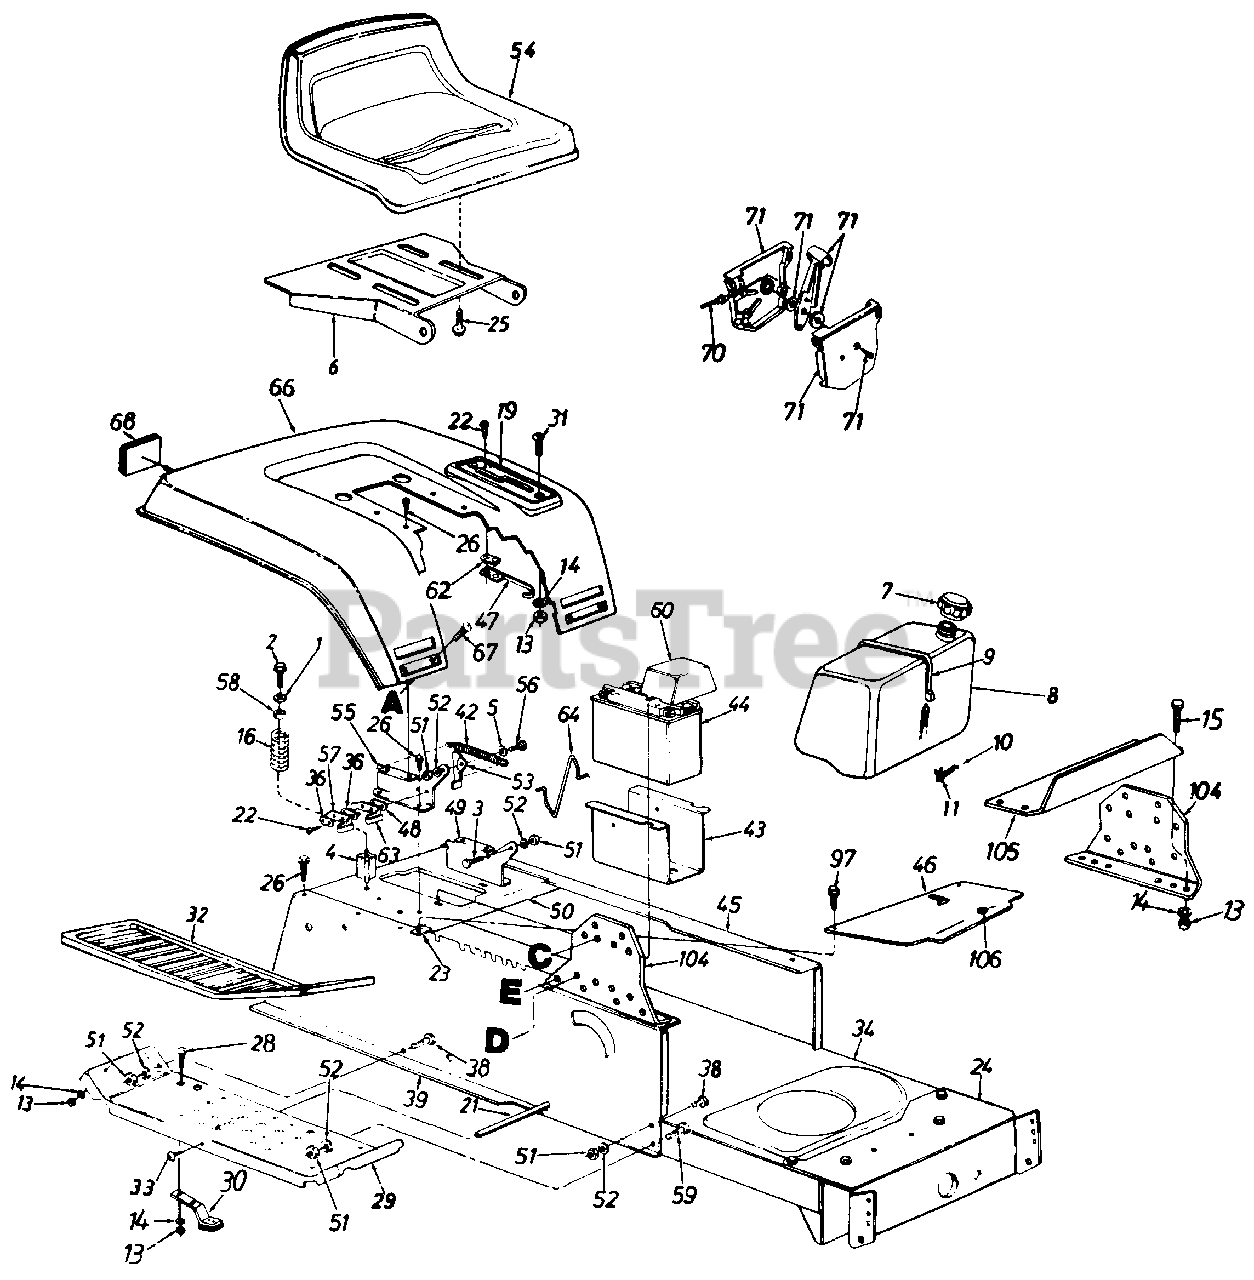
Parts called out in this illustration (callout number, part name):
1	Fl-Wash. .344" I.D. x .875"
2	Hex Wash. Hd. Tap Scr. 5/16-18 x 3.25" Lg.
3	Shld. Bolt .437" Dia. x .162"
4	Spring Spacer
5	Spr-Wash. .445" I.D. x .75
6	Seat Pivot Bracket
7	Fuel Cap w/o Gasket
8	Fuel Tank
9	Tie Strap
10	Fuel Line 15" Lg.
13	Hex Nut 1/4-20 thd.
14	L-Wash. 1/4" I.D.
15	Hex Bolt 1/4-20 x .62" Lg.
16	Compression Spring
19	Speed Control Index Brkt.
21	Running Board Rod
22	Hex Wash. Hd. AB-Tap Scr. #8 x .50" Lg.
23	Speed Nut #10Z
24	Front Pivot Bar
25	Hex Tap Scr. 3/8-16 x .75"
26	Hex Wash. Hd. AB-Tap Scr. 5/16 x .75" Lg.
28	Carriage Bolt 1/4-20 x .62"
29	Running Board (R.H. & L.H.)
30	Blade Brake Ass'y.
31	Truss Mach. Scr. 1/4-20 x .75" Lg.
32	Rubber Foot Pad-L.H.
33	Pan Hd. Cutting Scr. 5/16-18 x .75" Lg.
34	Lower Frame
36	Insulator Plate
38	Hex Bolt 5/16-18 x .75" Lg.
39	Upper Frame-R.H.
42	Extension Spring 5.31" Lg.
43	Battery Tray
44	12-V Battery
45	Upper Frame-L.H.
46	Shift Cover
47	Reverse Safety Switch
48	Insulator Boss Plate
52	L-Wash. 5/16" I.D.
53	Seat Lift Brkt.
54	Seat
56	Shld. Bolt .437" Dia. x .268"
57	Spring Switch
59	Hex Wash. Hd. Scr. 5/16-18 x .87" Lg.
60	Battery Cover
62	Insulator Nut Plate
63	Safety Switch (Seat)
64	Battery Tray Clip
68	Reflector
70	Throttle Wire
71	Throttle Control Box Ass'y.
97	Truss Mach. B-Tap Scr. #10 x .5" Lg.
